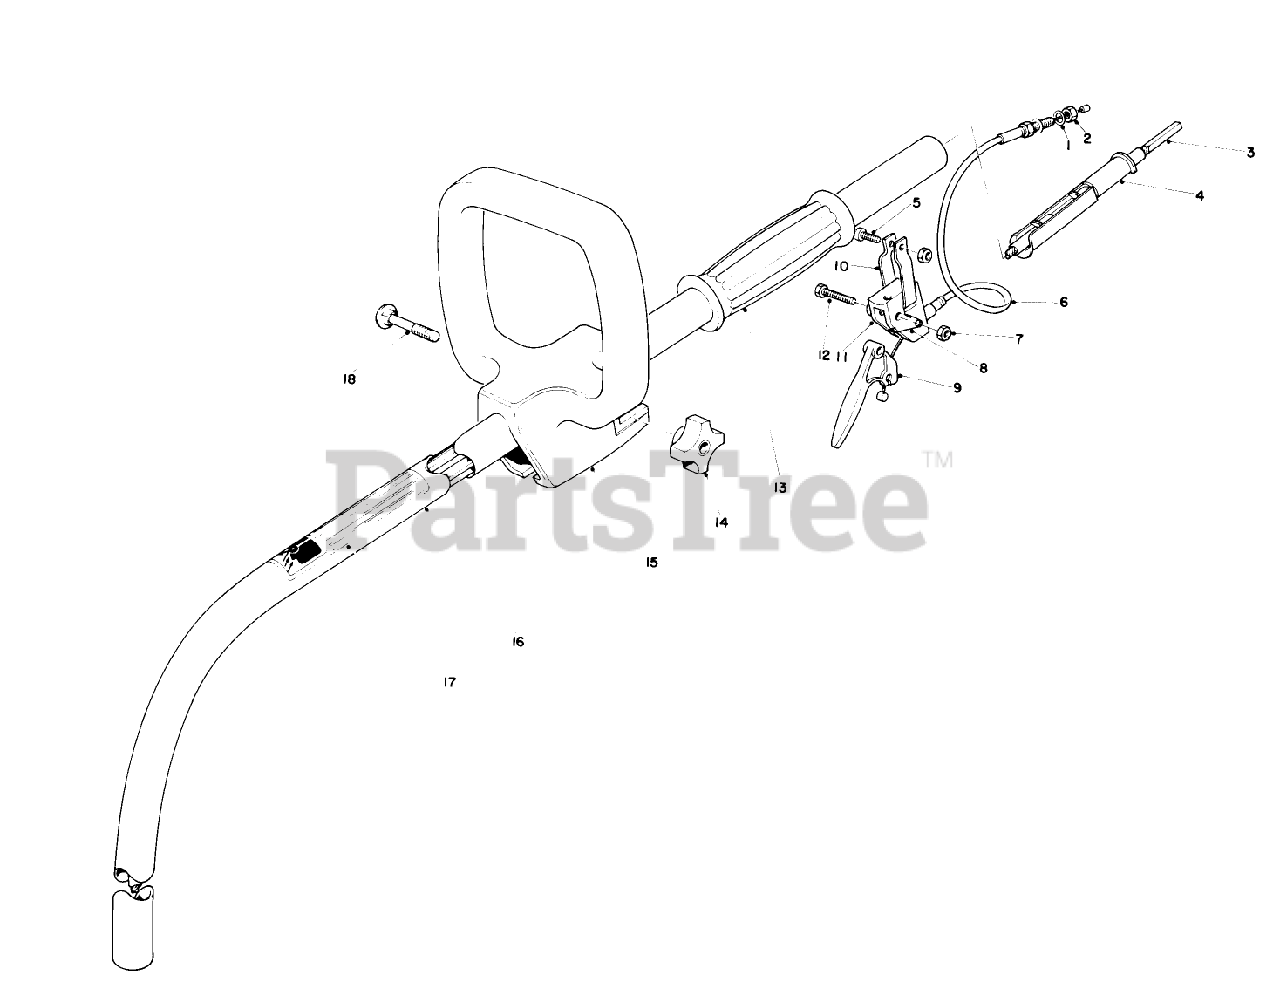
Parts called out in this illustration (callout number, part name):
1	WASHER-FLAT
2	NUT-JAM
3	Shaft-Flex
4	Insert-Pole End
5	SCREW-PPH
6	Cable-Throttle (Incl. Ref. #6 & 7)
7	NUT-LOCK, NI
8	Spring-Throttle Control
9	Lever-Throttle Control
10	Clamp-Throttle Control
11	Body-Throttle Control
12	Screw-Hex Head Machine
13	Grip-Handle
14	Knob
15	SECONDARY HANDLE
16	Tube-Shaft Housing
17	Decal Warning
18	BOLT-CARRIAGE
